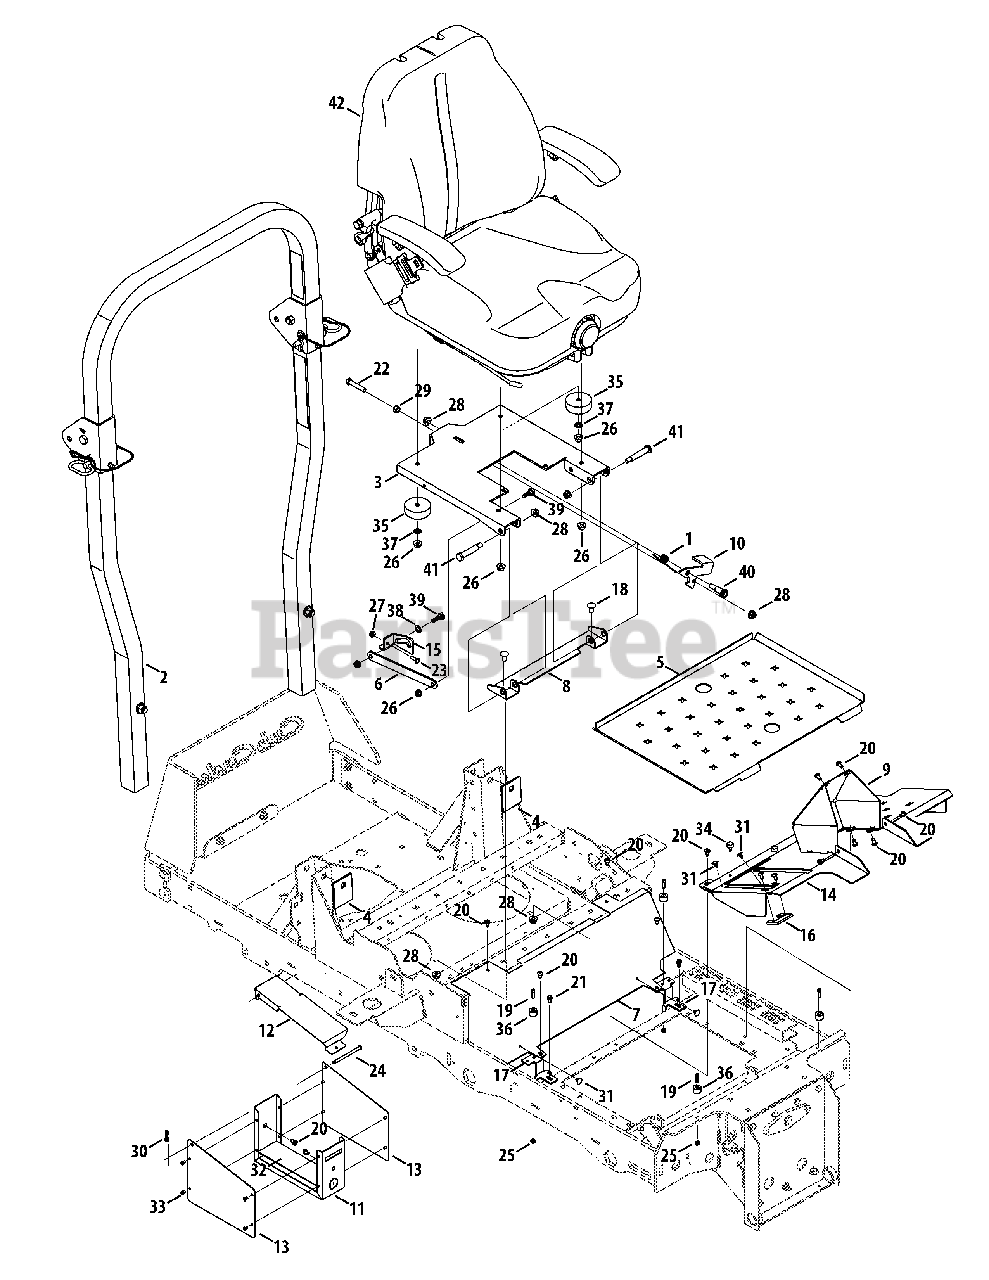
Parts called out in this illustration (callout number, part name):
1	Torsion Spring, .725 x 1.0 x .09
2	Folding ROPS Assembly
3	Seat Mounting Bracket
4	Deck Reinforcement Plate
6	Seat Lockout Bracket
7	Floor Panel Tray
8	Seat Mounting Bracket
10	Seat Lever Latch
12	Storage Box Lid
13	Storage Box Side Panel
15	Seat Lockout Mount
16	Stop Pedal Bracket
17	Frame Bracket, LH
18	Carriage Bolt, 3/8-16 x .75
19	Socket Head Screw, 10-24 x .75
20	Screw, 1/4-20 x .5
21	Hex Flange Screw, 1/4-20 x .500
22	Hex Cap Screw, 3/8-16 x 2.50
23	Hex Cap Screw, 1/4-20 x .75
24	Clevis Pin, .25 x 3.5
25	Nut, #10-24, Hexlock
26	Nut, 5/16-18, Flangelock
27	Nut, 1/4-20, Flangelock
28	Nut, 3/8-16, Flangelock
29	Nut, 3/8-16, Hex
30	Cotter Pin, Bow Tie
31	Clip, .250 Dia. x .500
32	Adhesive Pad
33	Rivet, 3/16 x .325
34	Bumper, .62 Dia. x .3
35	Rubber Bumper, 2.5 x 1.0
36	Rubber Bumper, .75 x .500
37	Washer, .344 x .688 x .065
38	Washer, .469 x .750 x .06
39	Shoulder Screw, .437 x .268, 5/16-18
40	Shoulder Bolt, .50 x .925, 3/8-16
41	Shoulder Bolt, .500 x 2.23, 3/8-16
42	Seat
